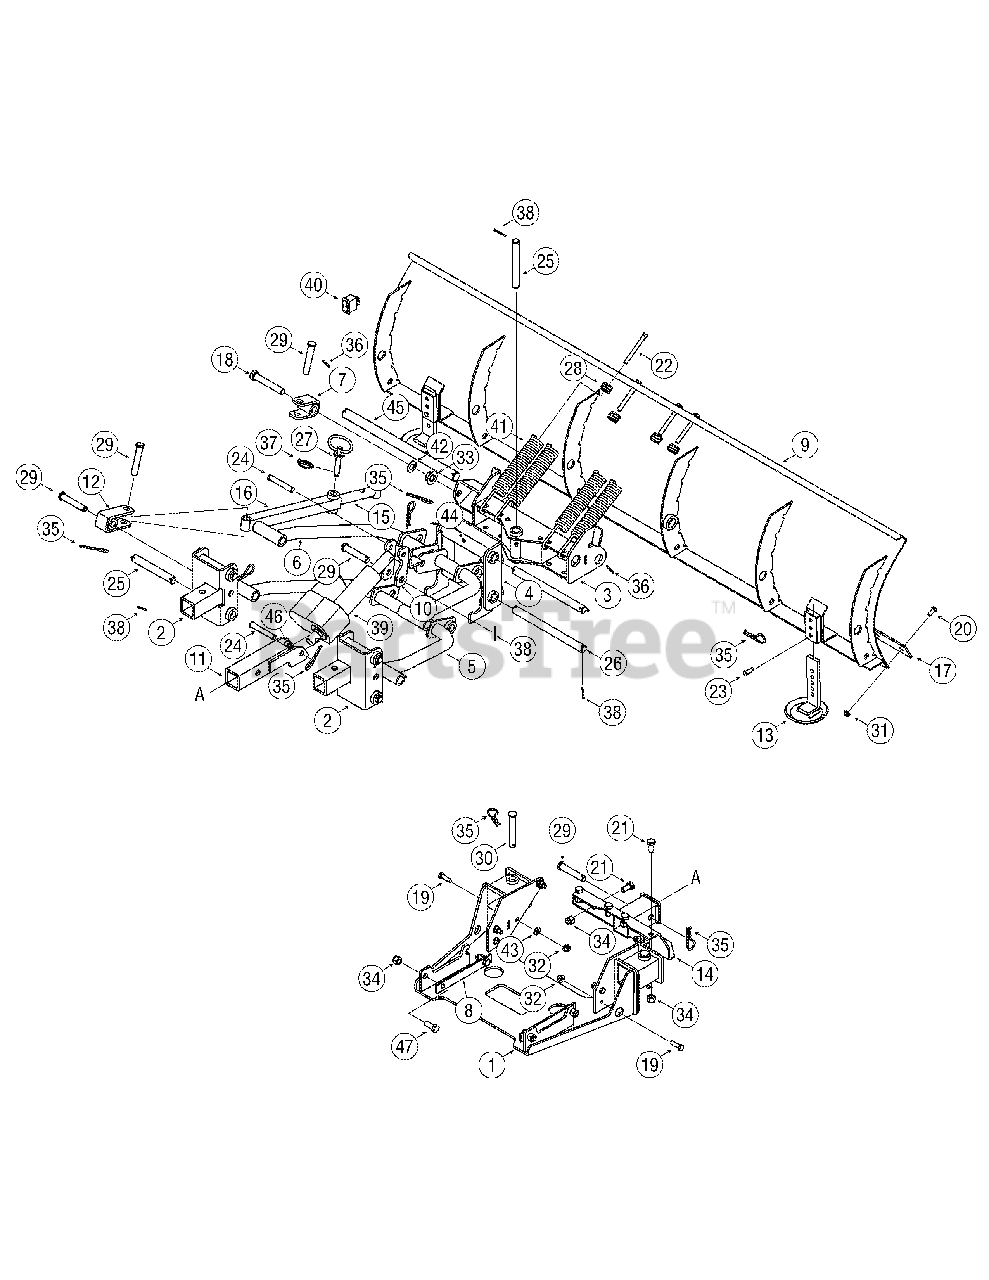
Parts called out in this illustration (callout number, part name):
15	Arm Assy., Adjust., Rod
18	Hhcs, 5/8-18 x 4.0
19	Hhcs, 3/8-16 x 1.25
20	Bolt, Crg., 5/16-18 x .875
21	Hhcs, 1/2-13 x 1.00
22	Hhcs, 3/8-16 x 3.50
23	Pin, Clevis, .375 Dia. X .969
24	Pin, Clevis, .50 x 3.25
25	Pin, Snow Blade, 5.825"
26	Pin, Snow Blade, 10.25"
27	Pin, Hitch, .50 x 2.5 Lg.
28	Spring Insert
29	Pin, Clevis, .625 Dia. X 3.0
30	Pin, Clevis, .625 Dia. X 4.0
31	Nut, Flglk., 5/16-18
32	Nut, Flglk., 3/8-16
33	Nut, Flg., 5/8-18
34	Nut, Hexlk., 1/2-13
35	Pin, Cotter, Int., .148 x 3.00
36	Pin, Cotter, 5/32 x 1.25
37	Pin, Lynch x .1875
38	Pin, Cotter, 1/8 x 1.25
39	Actr., Lift, Plow
40	Switch, Plow, Dirctnl, Up/Down
41	Spr., Adjust., Blade, 72"
42	Wash., Flat, .64 x 1.24 x .06
43	Wash., Flat, .385 x .87 x .09
44	Ftg., 3/16
45	Rod, Pivot, Blade, UV
46	Spcr., .505ID x .88 OD x .44
47	Hhcs, 1/2-13 x 1.25
